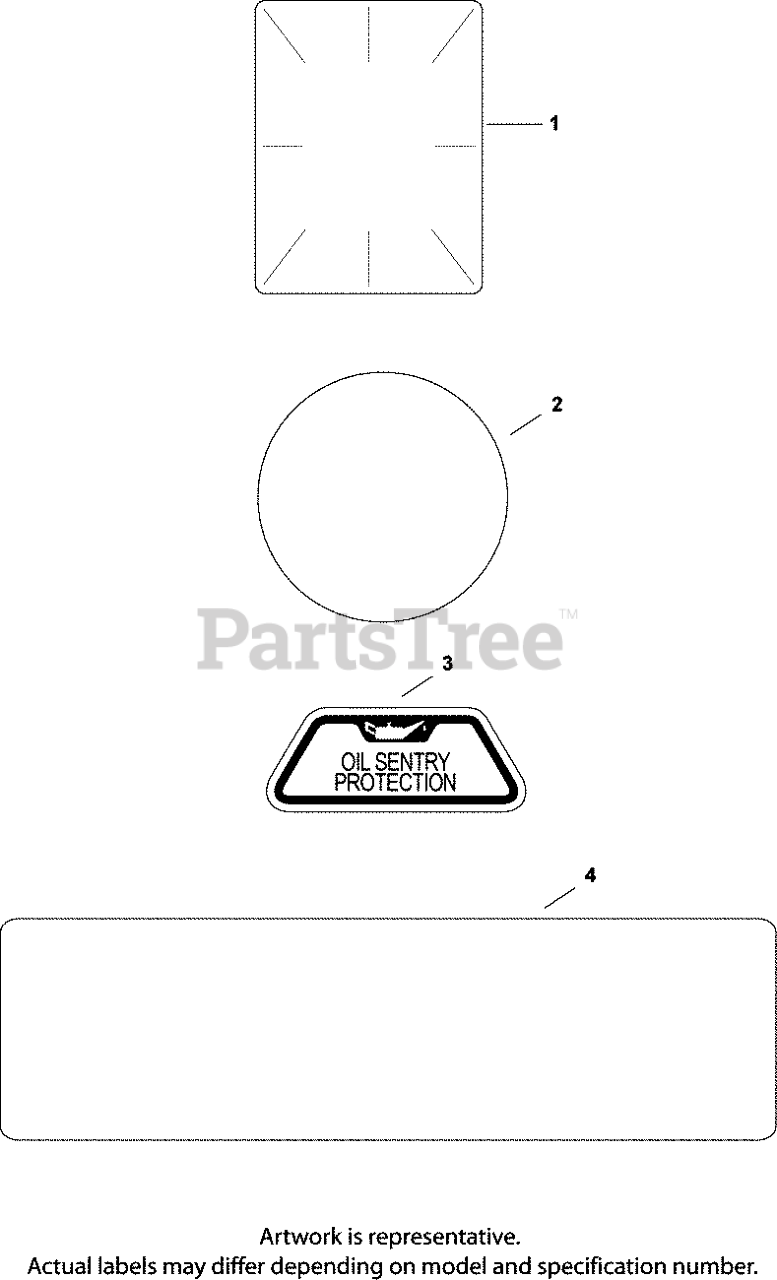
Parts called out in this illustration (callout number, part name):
1	DECAL, CLEAR LAMINATE USE 25 113 70-S
2	LABEL, (ROUND KOHLER GOLD)-USE 24 113 18
3	DECAL, OIL SENTRY - (#DSC)
4	DECAL, 23 HP - (#24113216S)
